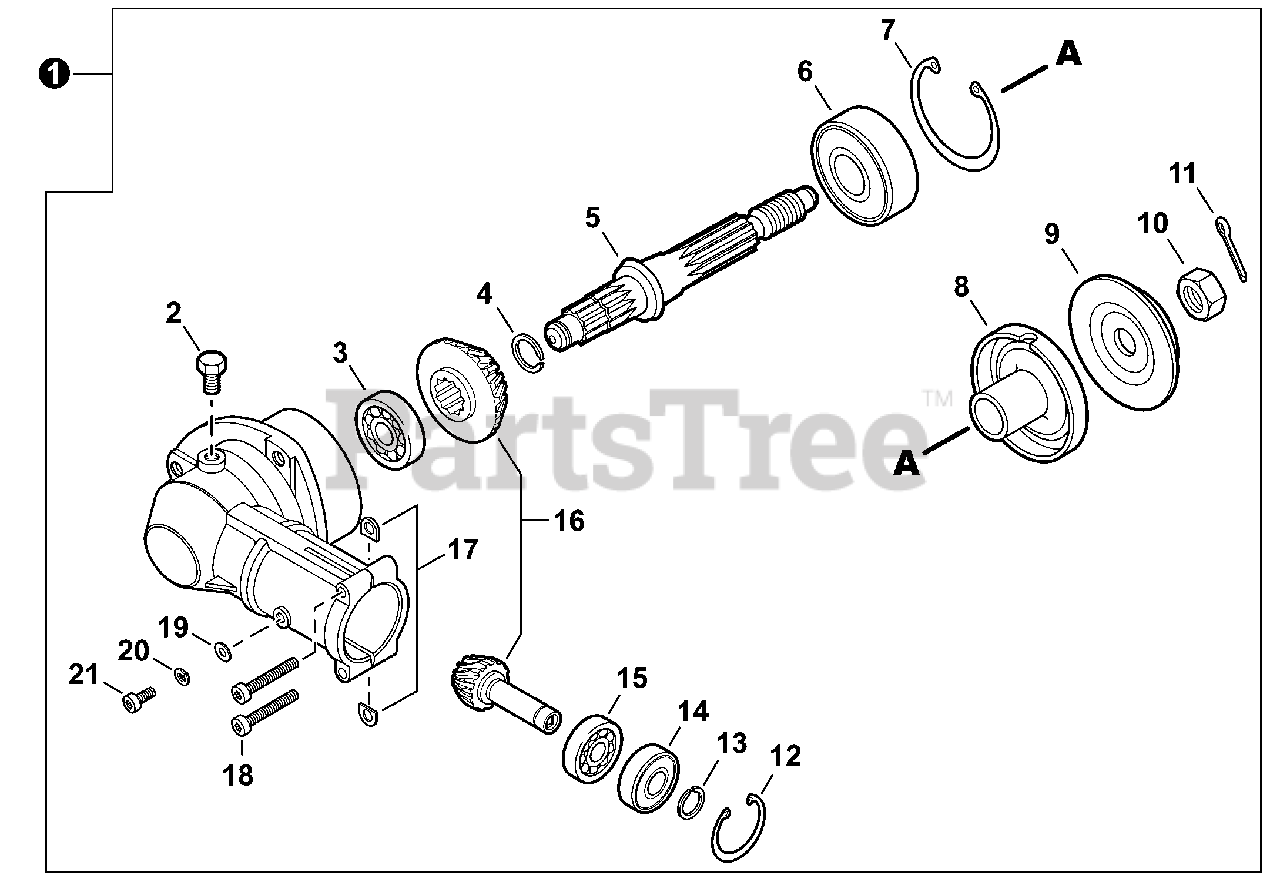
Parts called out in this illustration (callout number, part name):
1	GEAR CASE ASSY
2	BOLT M8×8
3	BEARING, BALL 629
4	RING, SNAP Ø12
5	SHAFT, GEAR
6	BEARING, BALL 6302
7	RING, SNAP Ø42
8	PLATE, ADAPTOR - UPPER
9	PLATE, ADAPTOR - LOWER
10	NUT 10×1.25 LH
11	PIN, COTTER 2×22
12	RING, SNAP Ø22
13	RING, SNAP Ø10
14	BEARING, BALL 6900-Z
15	BEARING, BALL 6900
16	GEAR SET
17	D-WASHER
18	BOLT, TORX 5×25
19	WASHER, FLAT 5.5×10×0.8
20	WASHER, SPRING 5
21	BOLT, TORX 5×10
